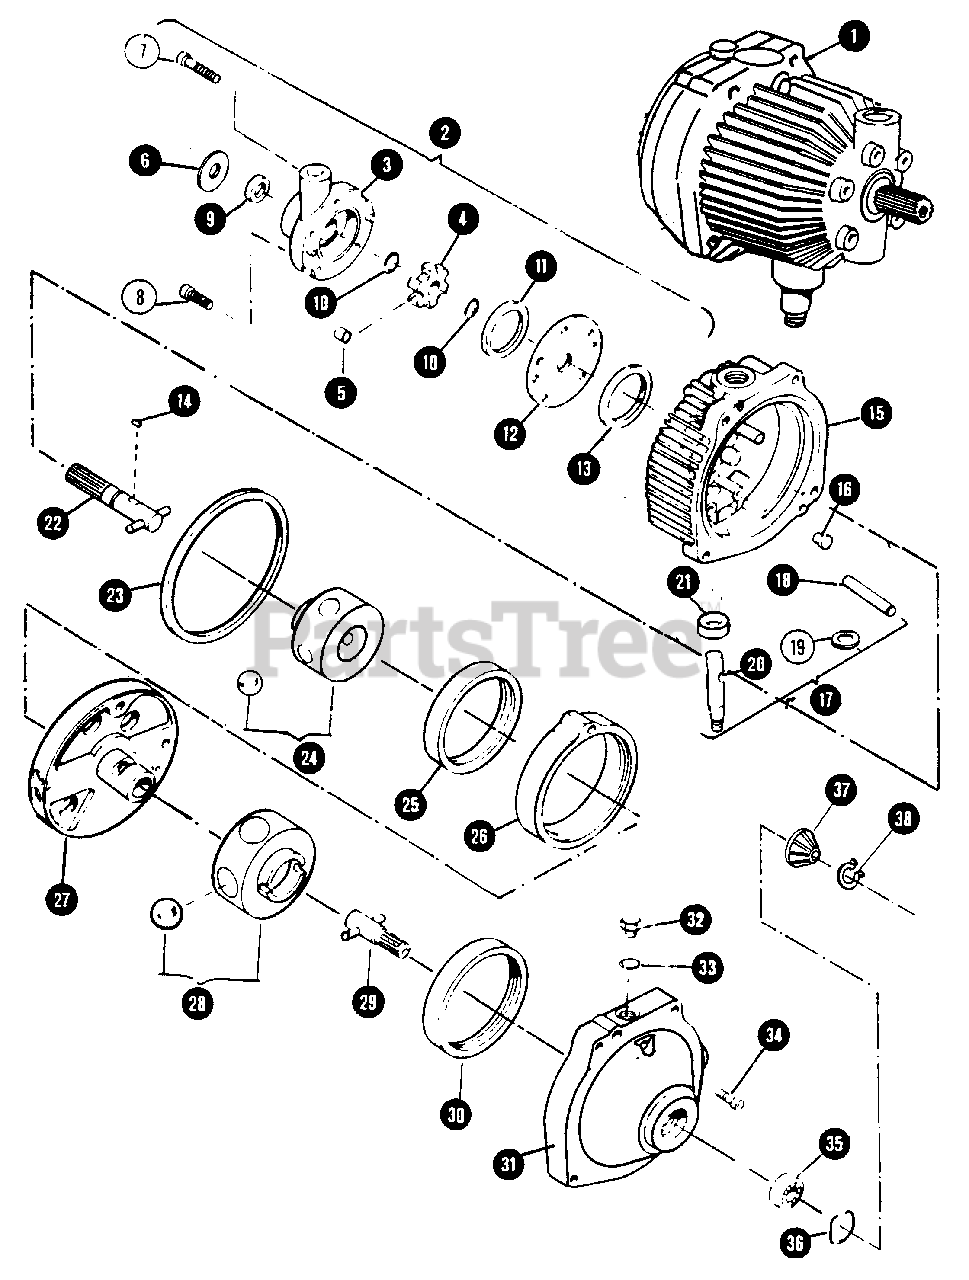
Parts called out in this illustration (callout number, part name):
1	HYDROSTATIC TRANSMISSION
2	KIT, CHARGE PUMP
3	BODY, CHARGE PUMP
4	CARRIER, CHARGE PUMP
5	ROLL, CHARGE PUMP
6	SHIELD, GRASS
7	SCREW, 5/16C x 1-3/4 SOCKET HEAD
8	SCREW, 5/16C x 1-1/4 SOCKET HEAD
9	SEAL OIL
10	RING CARRIER SNAP
11	RING, CHARGE PUMP SEALING
12	PLATE, CHARGE PUMP TO COVER
13	RING, PLATE TO COVER SEALING
14	PIN, CHARGE PUMP DRIVE
15	COVER ASSEMBLY, TRANSMISSION
16	BUTTON, COVER DAMPENER
17	KIT, CAM RING CONTROL
18	PIN, CAM RING CONTROL
19	WASHER, CONTROL
20	SHAFT, CAM RING CONTROL
21	SEAL, CAM RING CONTROL
22	SHAFT, INPUT - ASSEMBLY
23	RING, COVER TO BODY SEALING
24	ROTOR, BALL PUMP - ASSEMBLY
25	RACE, PUMP
26	RING, CAM
27	PINTLE, TRANSMISSION - COMPLETE ASSEMBLY
28	ROTOR, BALL MOTOR - ASSEMBLY
29	SHAFT, OUTPUT - ASSEMBLY
30	RACE, MOTOR ROTOR
31	BODY, TRANSMISSION
32	PLUG, O-RING
33	O-RING
34	SCREW, 5/16C x 1-1/4 SOCKET HEAD
35	BEARING, OUTPUT SHAFT
36	RING, RETAINING
37	PINION-GEAR
38	RING, RETAINING
